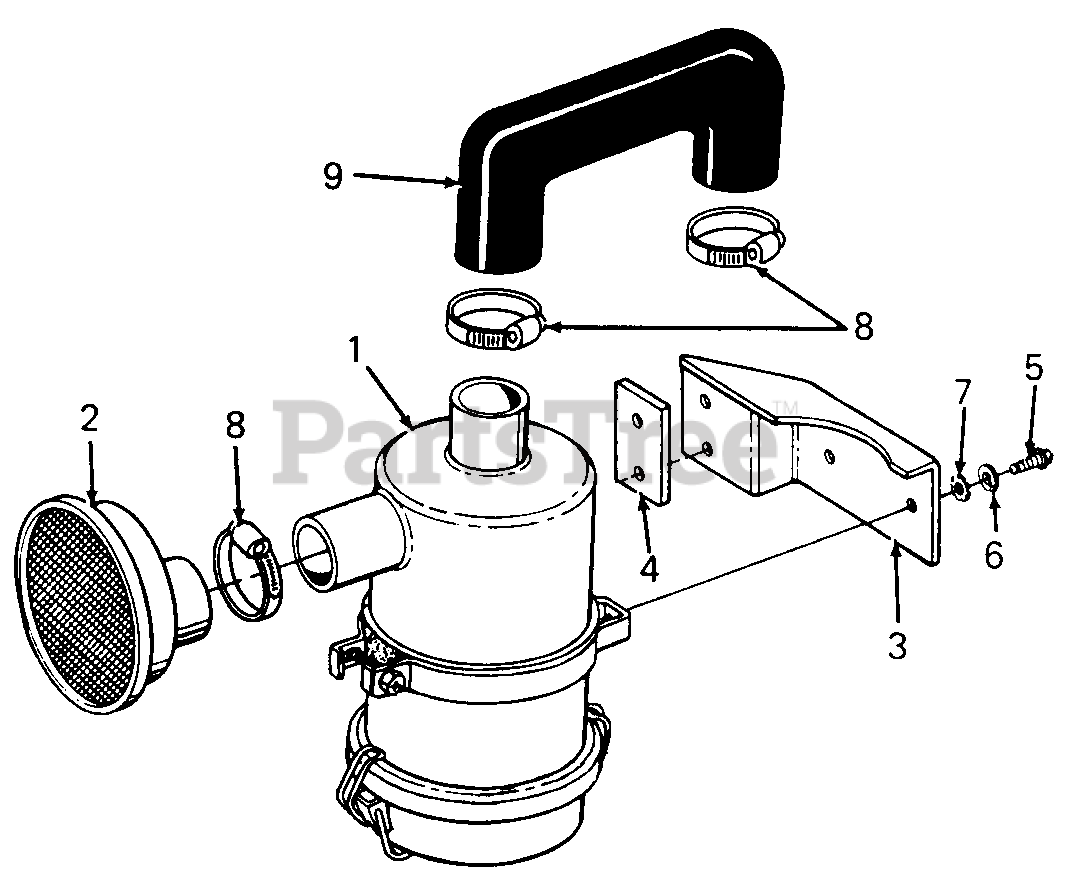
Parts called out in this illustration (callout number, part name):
1	Cleaner Assy, Air
2	Intake Assy, Air
3	Bracket, Air Cleaner Support
4	Pad, Isomount
5	Screw, Hex Cap, M8-1.25 X 20 mm Lg GR5
6	Washer, Lock, 5/16
7	Washer, Int Ext Lock, 5/16 ID X .88 OD
9	Hose, Air Intake
